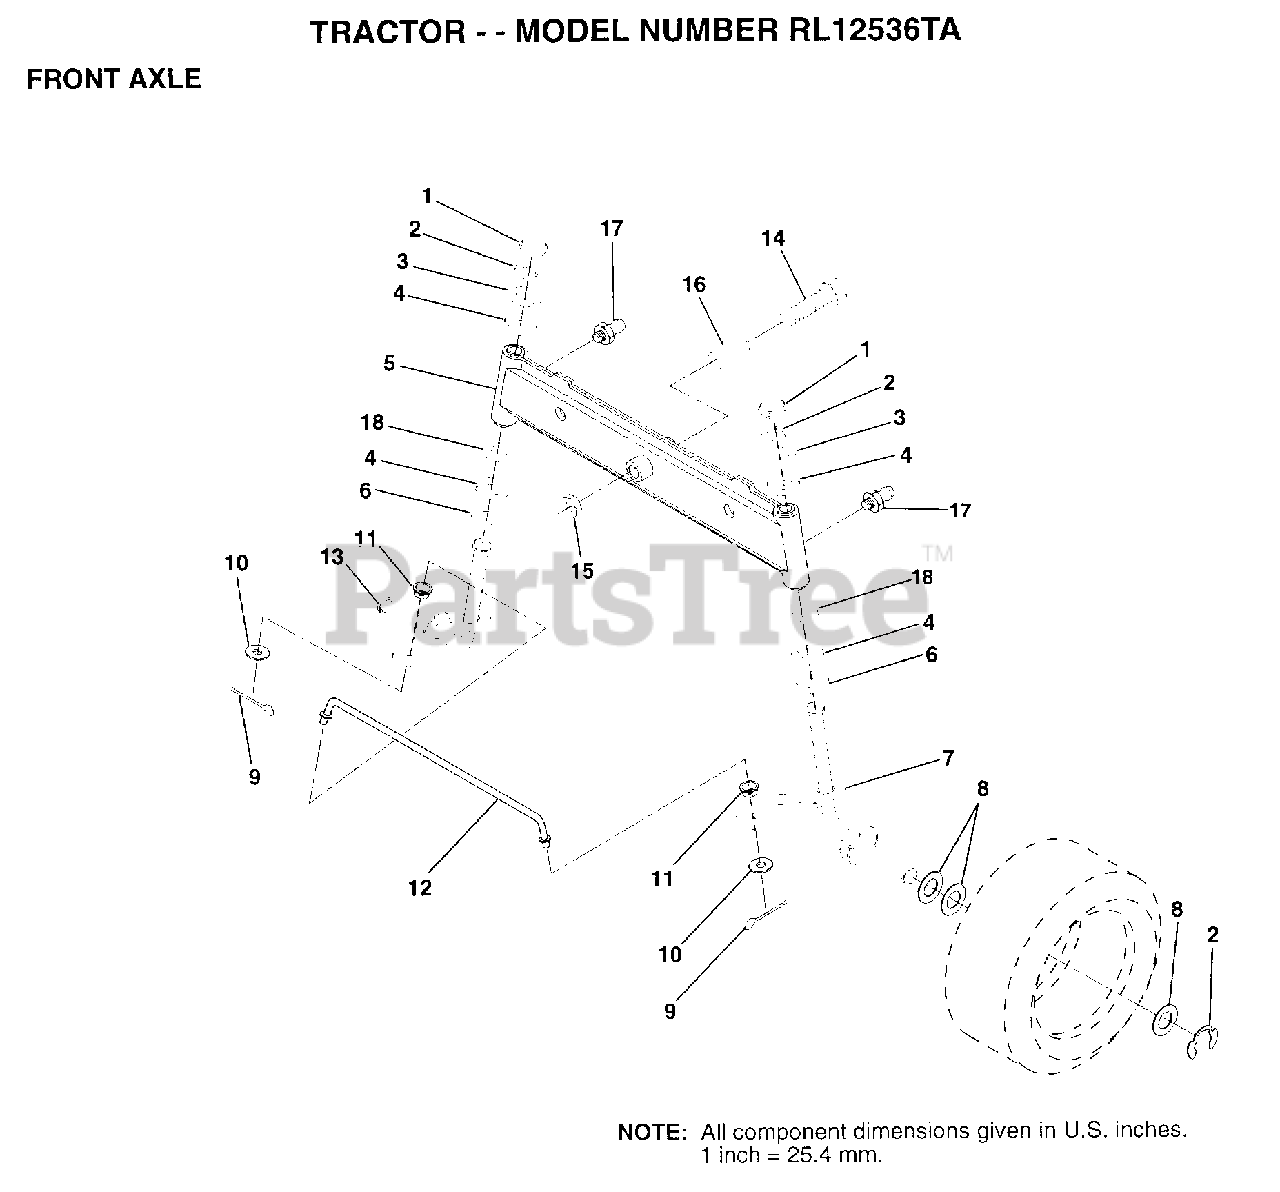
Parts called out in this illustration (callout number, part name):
1	CAP
2	RING
3	WASHER
4	COL. SRTG. BEAR.
5	AXLE ASM FRONT
6	WASHER .T
7	SPINDLE ASM RH
8	WASHER
9	COTTER PIN
10	WASHER
11	BUSHING.DRAGLINK
12	TIE ROD
13	SPINDLE ASM LH
14	BOLT HEX 5/8-11
15	"NUT-LOC,FLANGE LT"
16	BEARING
17	ZERK M
18	WASHER
